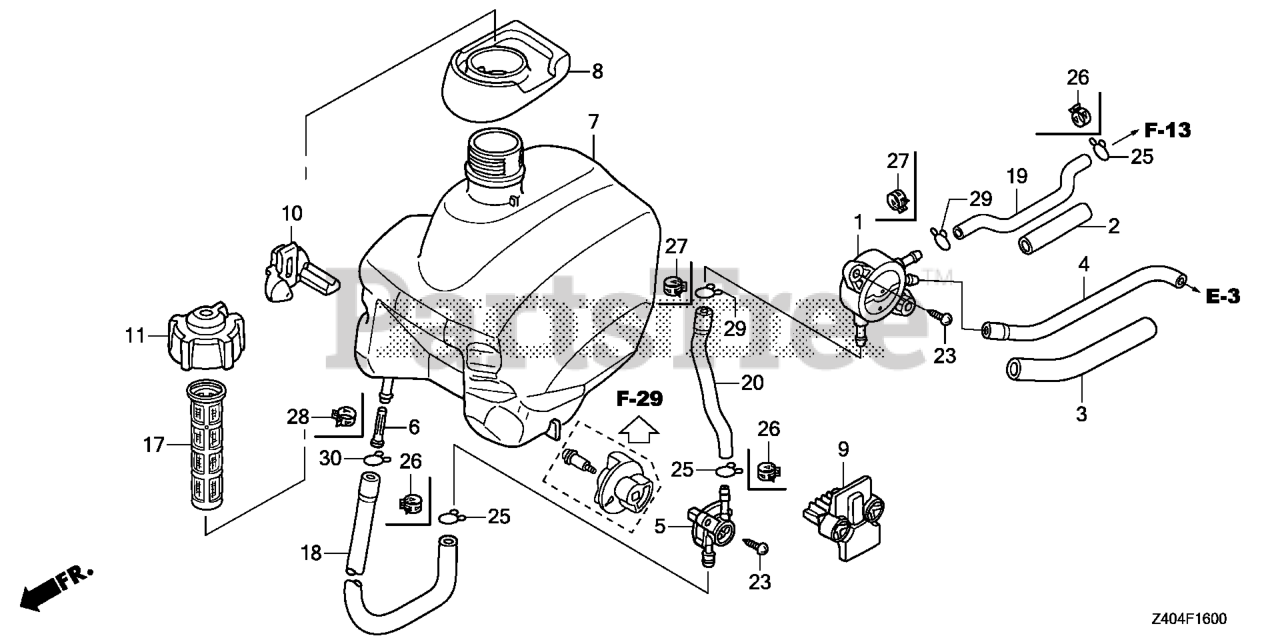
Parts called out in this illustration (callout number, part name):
1	PUMP ASSY., FUEL (MSDS)
2	RUBBER A, SUPPORTER
3	RUBBER B, SUPPORTER
4	TUBE, DIAPHRAGM
5	PETCOCK ASSY.
6	FILTER, FUEL
7	TANK, FUEL (NOT AVAILABLE)
8	SEAL, FUEL FILLER NECK
9	RUBBER R, TANK MOUNTING
10	RUBBER L, TANK MOUNTING
11	CAP ASSY., FUEL TANK
17	FILTER, FUEL
18	TUBE, FUEL TANK (FKM)
19	TUBE, A FUEL
20	TUBE B, FUEL (FKM)
23	SCREW, TAPPING (5X20) (PO)
26	CLIP, TUBE (D8)
27	CLIP, TUBE (D8.5)
28	CLIP, TUBE (10.5MM)
